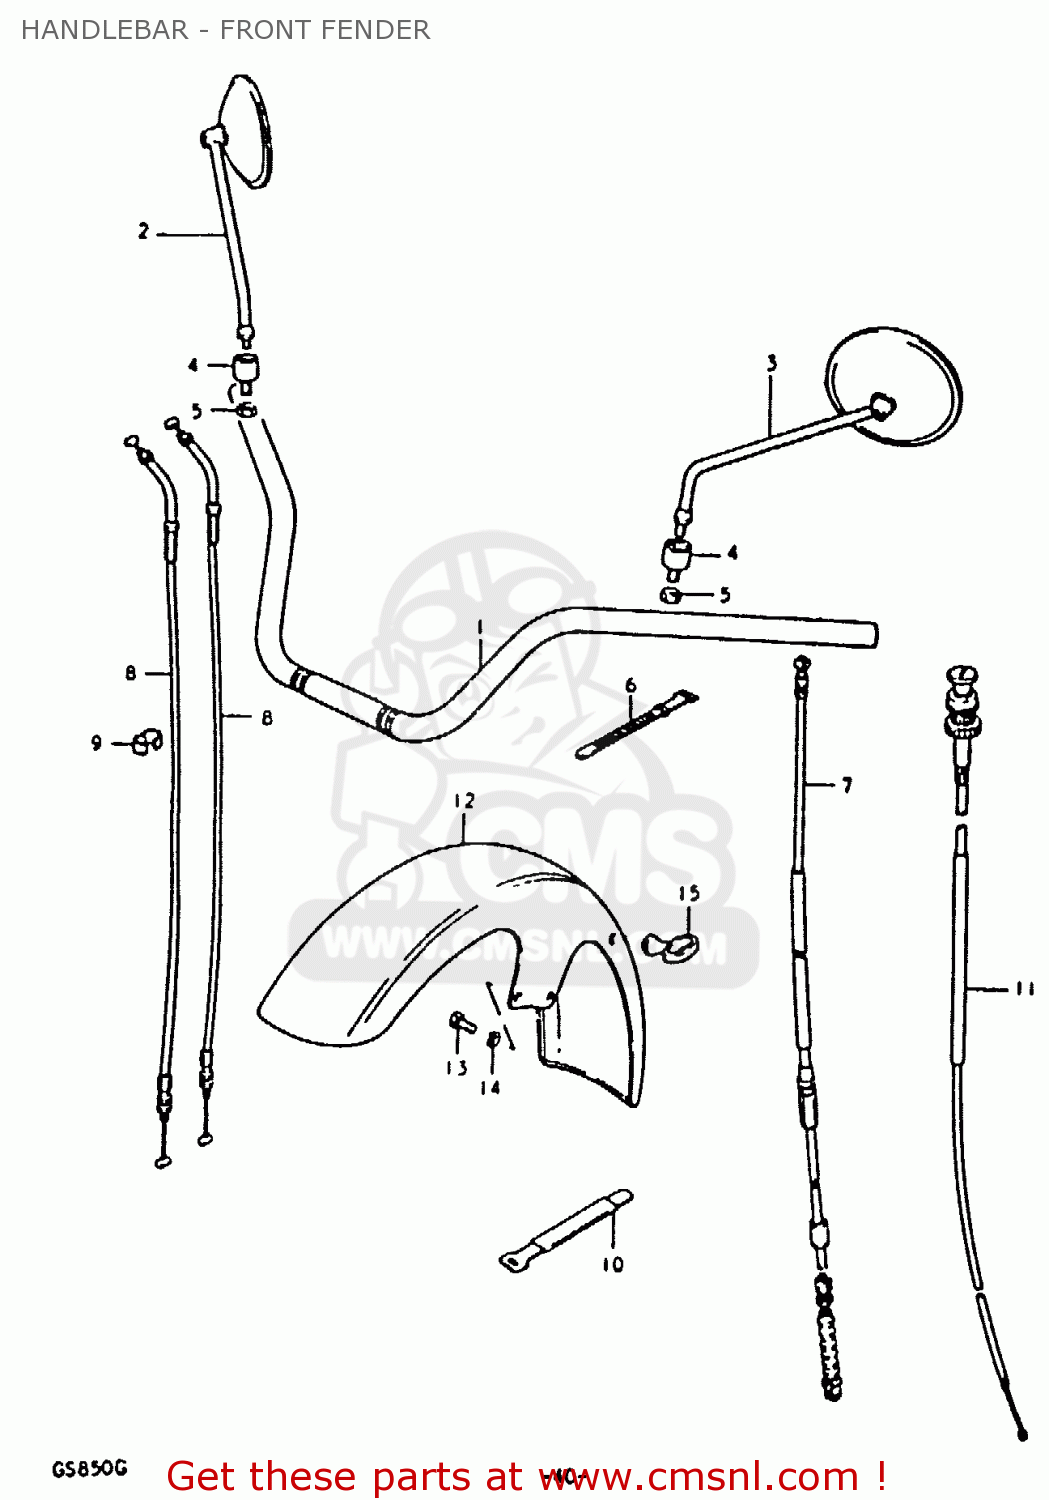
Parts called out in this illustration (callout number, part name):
1	HANDLEBAR
2	MIRROR ASSEMBLY,RIGHT
3	MIRROR ASSEMBLY,LEFT
4	CUSHION,REAR VIEW MIRROR
5	NUT
6	CLAMP(L:120)
7	CABLE ASSY,CLUTCH
8	CABLE ASSY,THROTTLE
9	CLIP
10	CLAMP
11	CABLE ASSY,STARTER
12	FENDER,FR
13	BOLT
14	LOCK WASHER
15	GUIDE,CABLE
